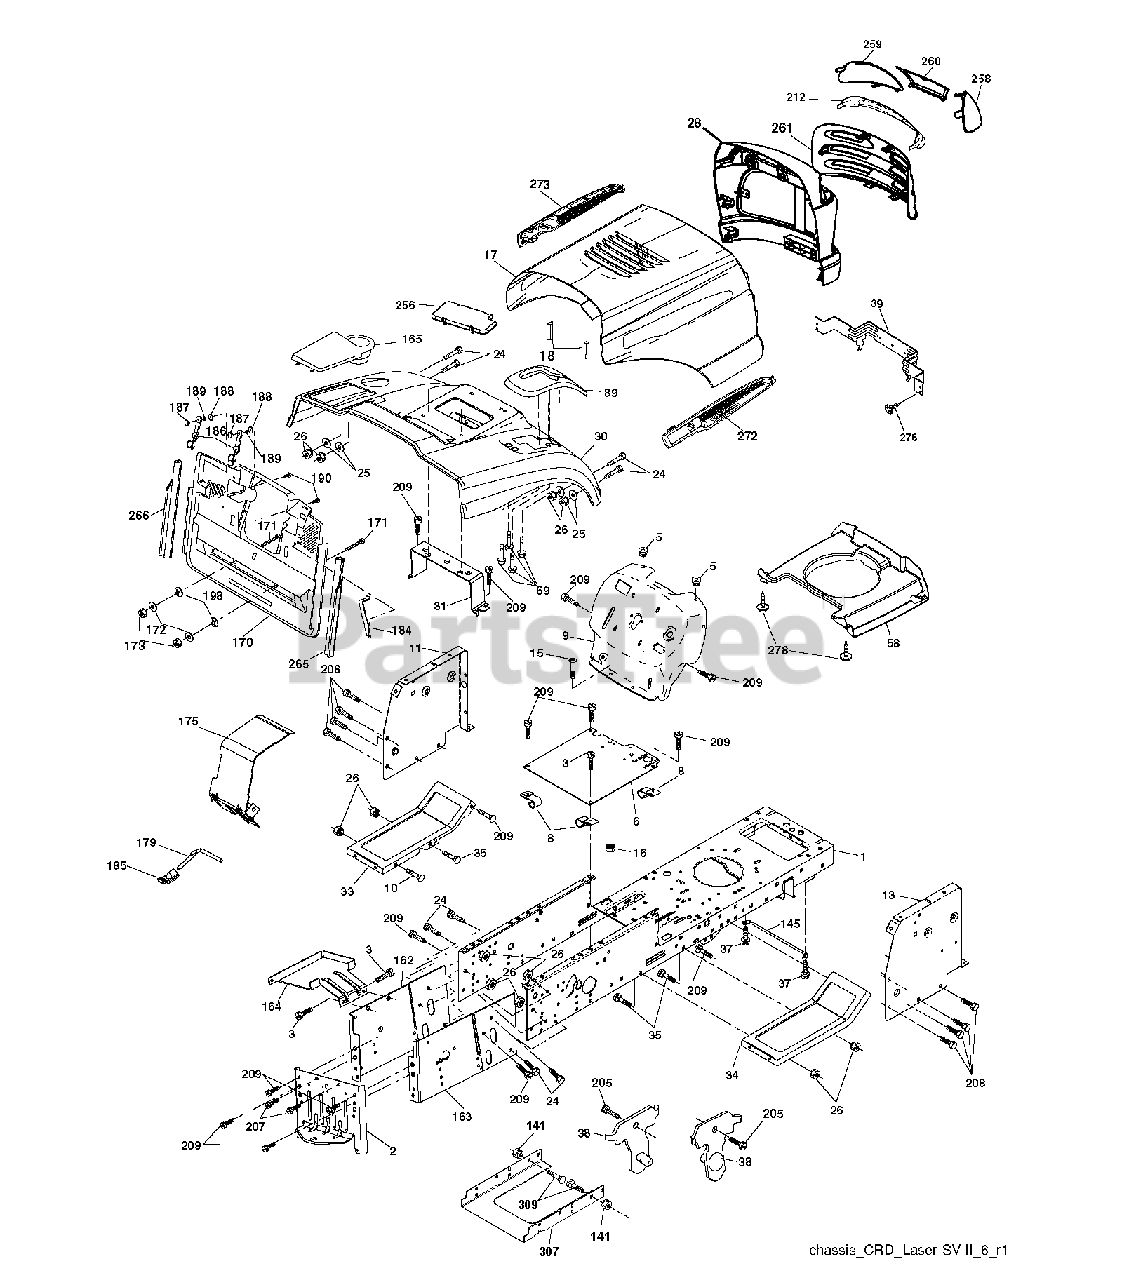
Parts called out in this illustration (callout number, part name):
1	CHASSIS
3	SCREW 3/8-16X3/4
5	BUMPER.RUBBER.HOOD
8	CLIP,INSULATOR
10	BOLT D
11	PANEL.DASH.LH.LTX
13	PANEL ASM, DASH RH
16	NUT
18	BUMPER.HOOD.LARGE.1.75"
25	WASHER
26	NUT
31	BRACKET SUPPORT FENDER
39	BRACKET PIVOT
69	SCREW.HI-LO.CONSOLE
141	NUT LOCK FLG 3/8-16 UNC
145	ROD.PIVOT.HOOD
164	SUPPORT
171	BOLT
172	WASHER
186	LATCH ASSY
187	WELDNUT
189	LOCKWASHER
207	SCREW, 5/16-18 X 1/2
208	SCREW 3/8-16X1/2
209	SCREW, 3/8-16X3/4
278	SCREW.#10 X 0.750.BOS THREAD
